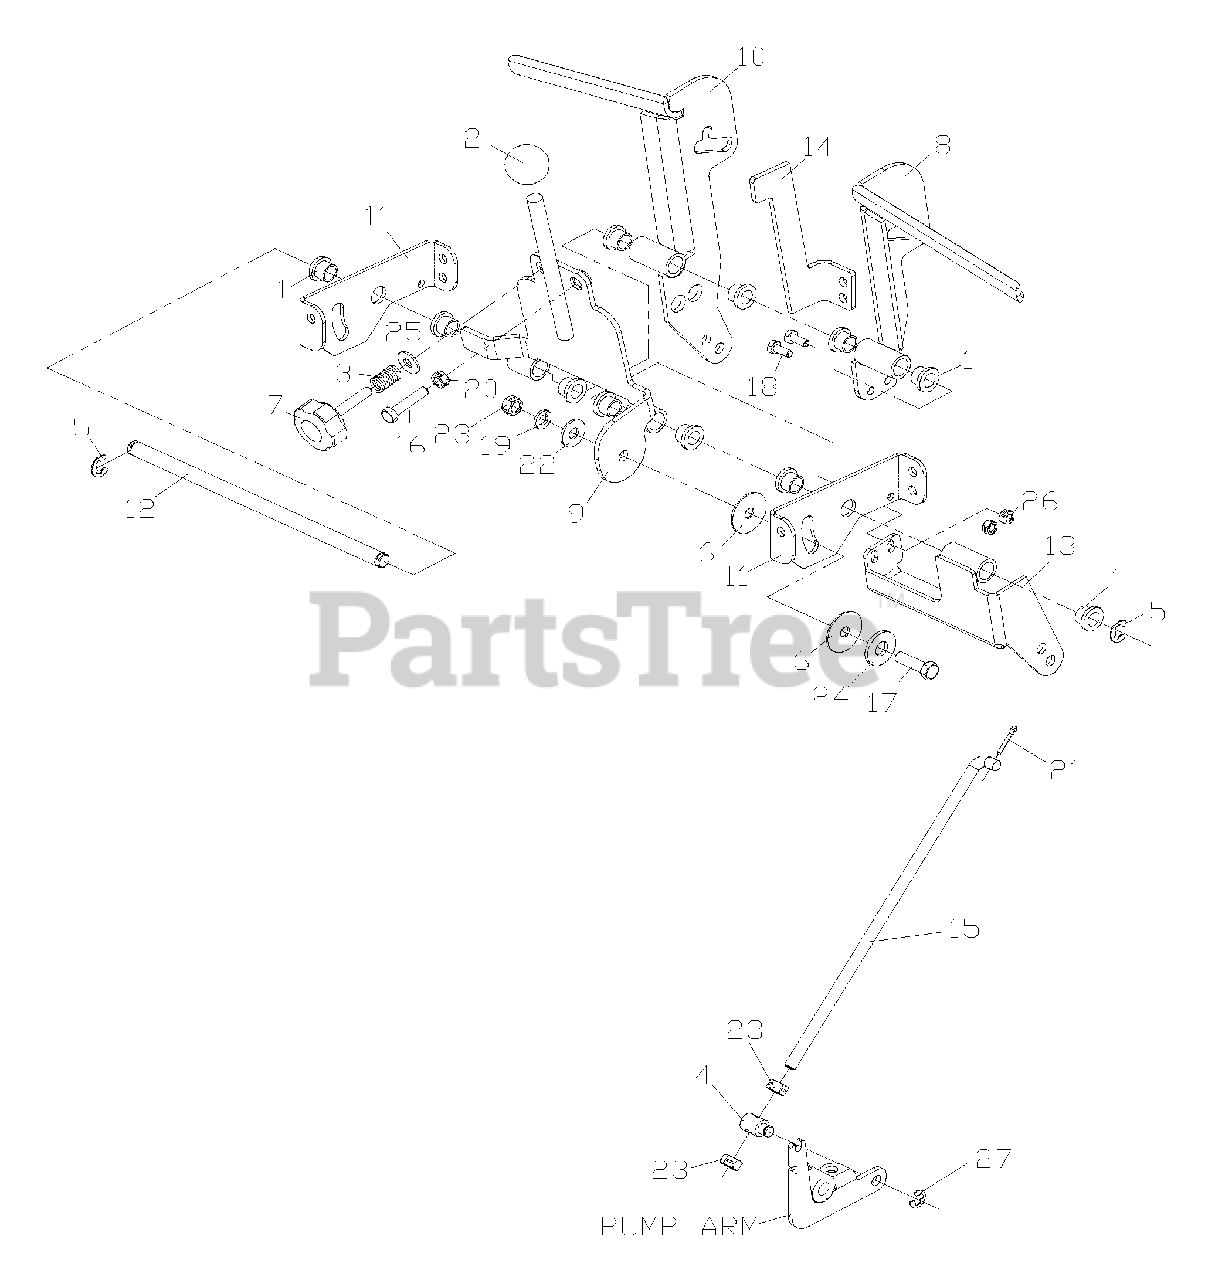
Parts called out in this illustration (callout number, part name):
1	FLANGED BUSHING
5	E-RING 1/2
6	WASHER FRICTION
8	PADDLE, LEFT
9	NEUTRAL BAR
10	PADDLE, RIGHT
11	CROSS BRACE
14	STOP PLATE
15	DRIVE LINKAGE
16	HCS 5/16 X 1.500
17	HCS 3/8 X 1.250
18	HCS 1/4 X 625
19	WASHER 3/8 LOCK
20	NUT 5/16 CTR. LOCK
21	COTTER PIN
22	WASHER 3/8 FLAT
23	NUT 3/8 CTR. LOCK
24	WASHER 1/2 FLAT
25	WASHER 5/16 FLAT
26	NUT 1/4 CTR. LOCK
